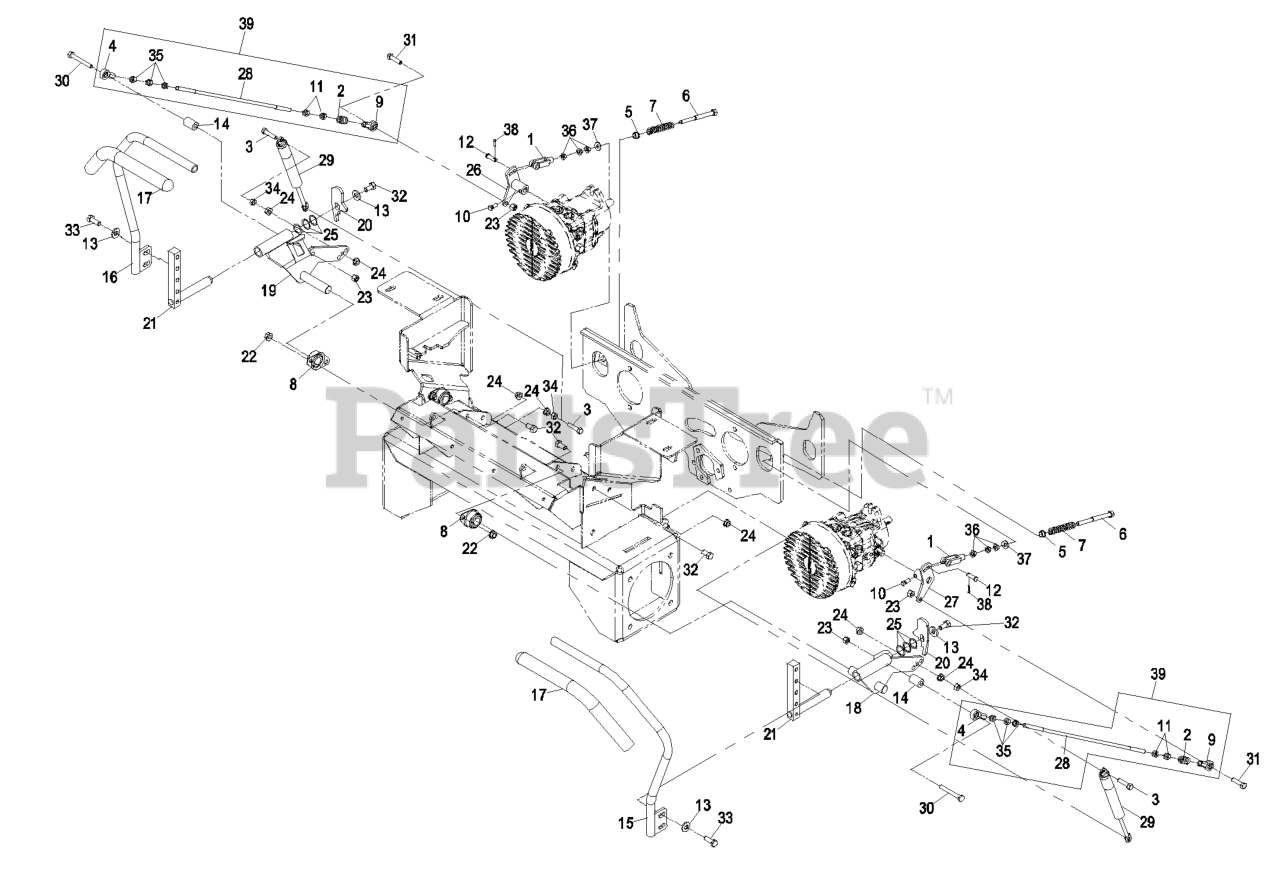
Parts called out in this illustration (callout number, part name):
1	YOKE-ADJUSTABLE
2	SPRING-COMPRESSION
3	SCREW-HH
4	BALLJOINT-RH
5	BUSHING-FLANGED
6	BOLT-RETURN, NEUTRAL
7	SPRING-RETURN, NEUTRAL
8	BEARING-FLANGE, SIDE
9	BALLJOINT-LH
10	SCREW-SET
11	NUT
12	PIN-CLEVIS
13	WASHER-BELLEVILLE
14	SPACER-HYDRO CONTROL, LH
15	ASM,LH LEVER/GRIP
16	ASM.RH LEVER/GRIP
17	GRIP,CONTROL LEVER
18	WLD,LH FMZ MOTION CTRL (P
19	WLD,RH FMZ MOTION CTRL(PL
20	TAB,FMZ MOTION CNTRL (PLA
21	WLD,FR CONTROL SHAFT(PLTD
22	NUT-HHF, WHIZ
23	NUT-LOCK, NI
26	WLD,PR PUMP CTRL RH
27	WLD,PR PUMP CTRL LH
28	LINK,TRACKING ROD FMZ (PL
29	DAMPER-CONTROL, MOTION
30	SCREW-HH
31	SCREW-HH
32	SCREW-HH
33	SCREW-HH
34	NUT-HEX
35	NUT-HEX
36	NUT-JAM
37	WASHER-FLAT
38	PIN-COTTER
39	ASM,FMZ PR TRACKING ROD
